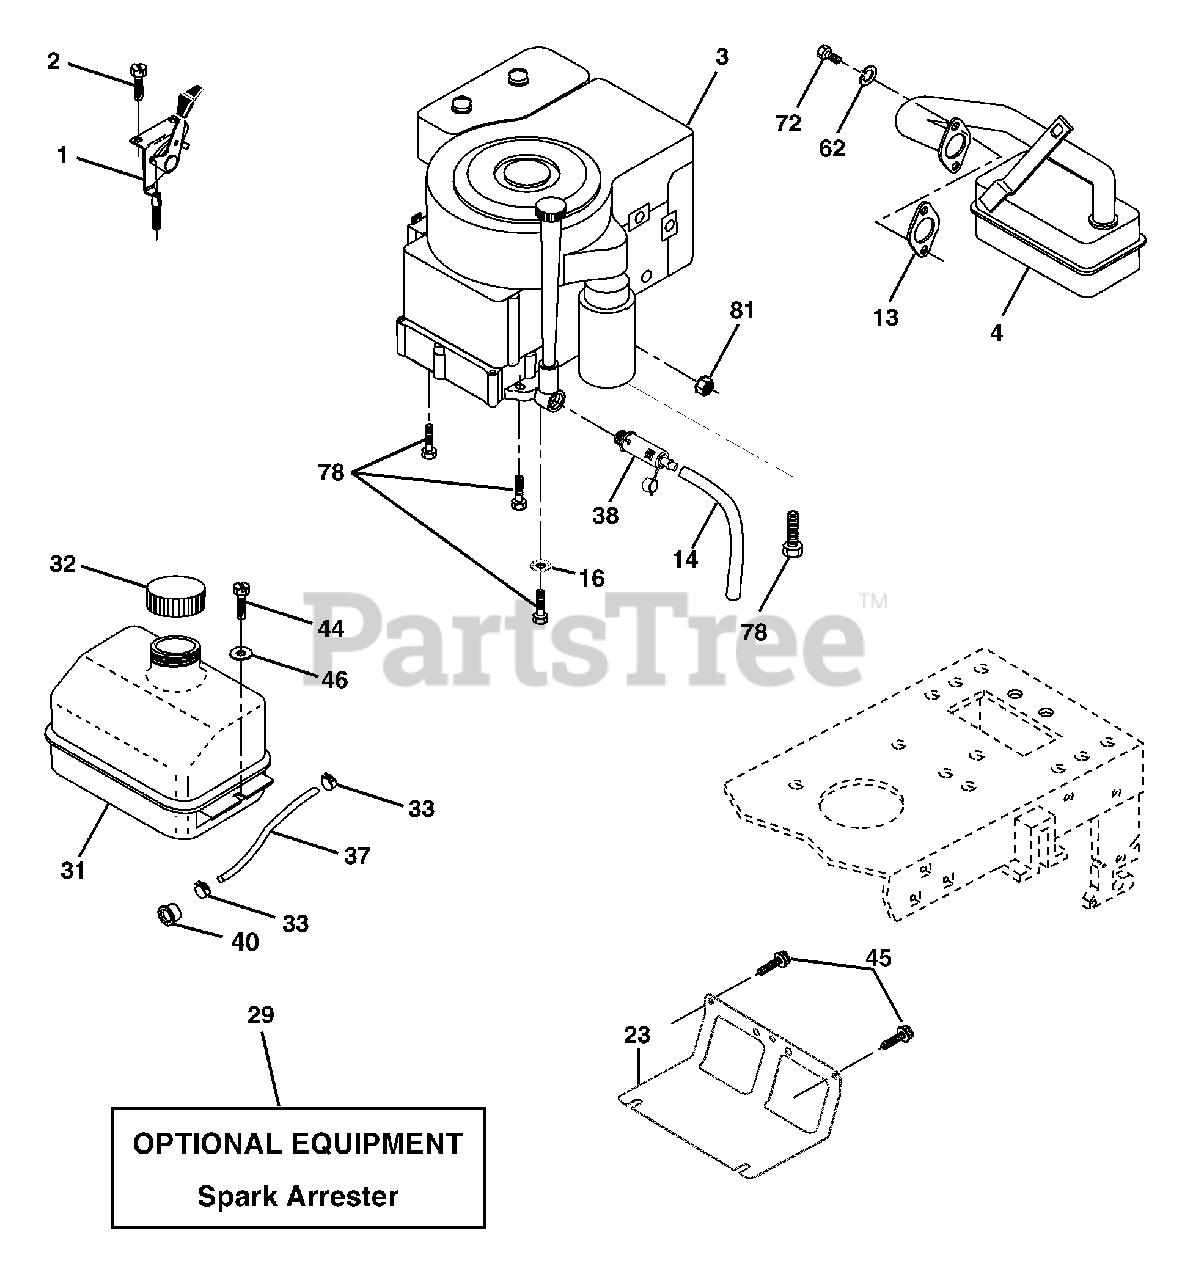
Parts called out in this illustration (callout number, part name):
1	Control Th/ch Flag
2	Screw Hex Thd Cut 1/4-20 x 1/2
4	Muffl er
13	Gasket Eng
14	Tube Drain Oil Easy
16	Washer Lock Ext Tooth 3/8
23	Shield Brn/Dbr Guard
29	Kit Spark Arrestor (Flat Scrn)
31	Tank Fuel Front
32	Cap Asm Fuel W/sym Vented
33	Clamp Hose Black
37	Line Fuel 20"
38	Plug Drain Oil Easy
40	Bushing Snap Nyl Blk Fuel Line
44	Screw Hexwsh Thdrol 1/4-20x3/4
45	Screw Hexwsh Thdr 3/8-16 x 3/4
46	Washer 9/32 X 7/8 X 16 Ga
62	Washer Lock Hvy Hlcl Spr 5/16
72	Screw Hex Hd Cap 5/16-18 x 3/4
78	Screw 3/8-16x1-1/4
81	Nut Keps Hex 1/4-20 UNC
